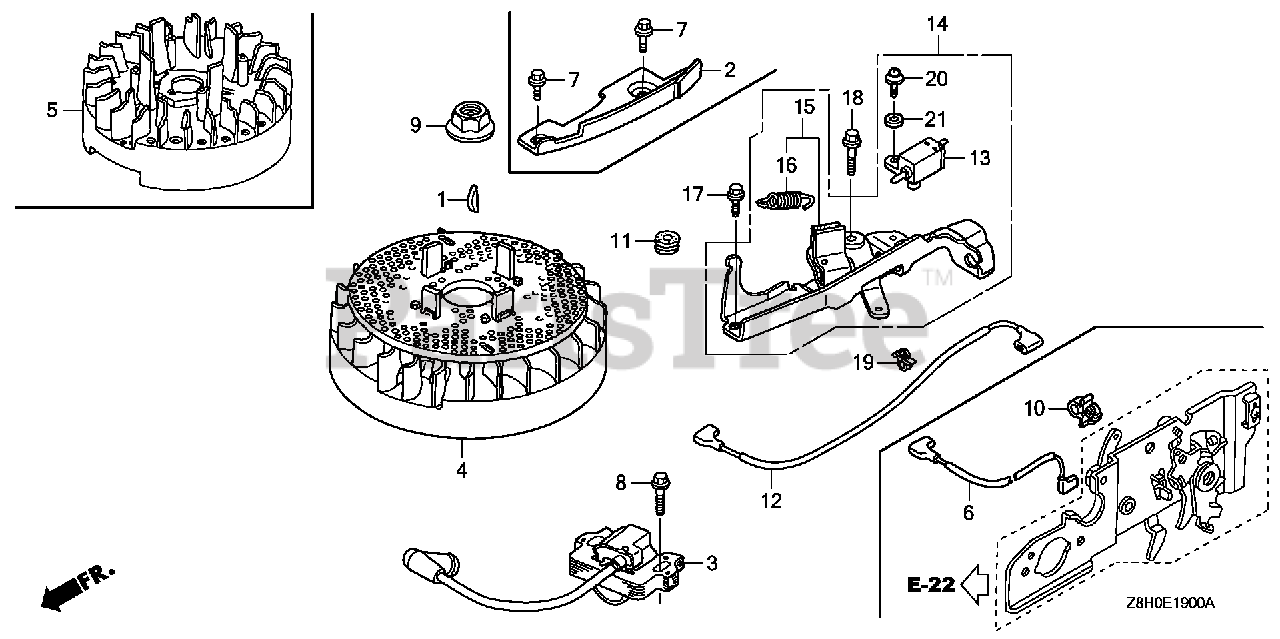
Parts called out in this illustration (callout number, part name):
1	KEY, SPECIAL WOODRUFF (25X18)
3	COIL ASSY., IGNITION (USE FOR F/W OF TEC) (TEC)
4	FLYWHEEL ASSY. (TEC) (USE FOR IGN. COIL OF TEC)
8	BOLT, FLANGE (6X20) (CT200)
9	NUT, SPECIAL (14MM)
12	WIRE, STOP SWITCH
13	SWITCH ASSY., ENGINE STOP (N.C)
14	BRAKE ASSY.
16	SPRING, BRAKE LEVER
17	BOLT, FLANGE (6X14) (CT200)
18	BOLT, FLANGE (6X23) (CT200)
19	CLIP A, CABLE (3.8MM BLACK) (NIFCO)
20	SCREW-WASHER (4X12)
21	WASHER, PLAIN (4MM)
